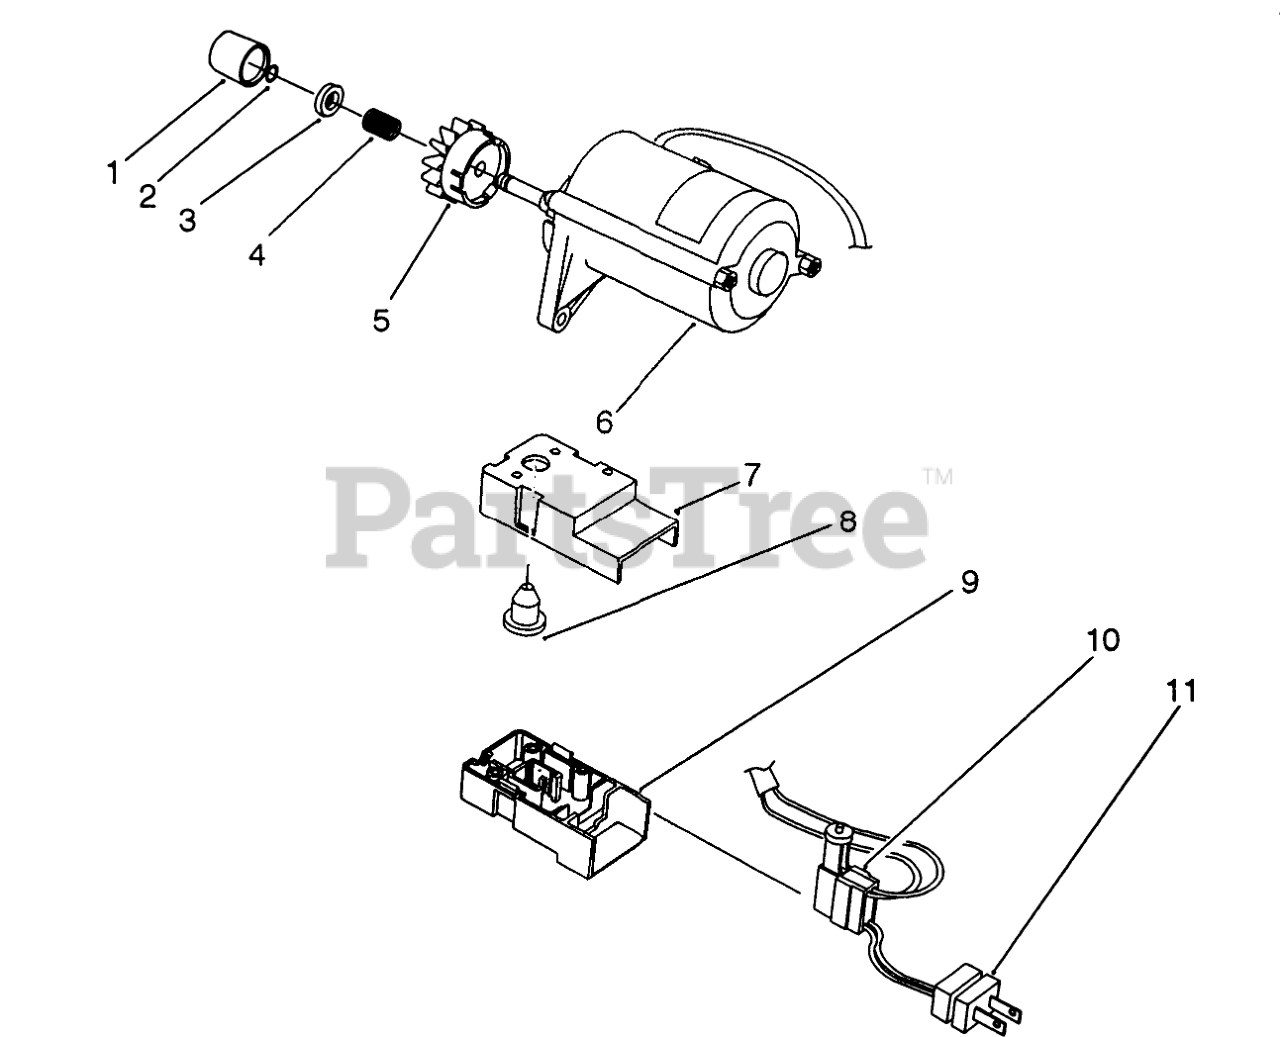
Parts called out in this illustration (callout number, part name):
1	CAP-PINION
2	RING-LOCK
3	PINION STOP
4	SPRING
5	PINION ASM
6	ASM-Switch Housing
7	Cap-Switch Housing
8	BOOT-SWITCH
9	OBS BASE X
10	SWITCH-STARTER
11	Plug
